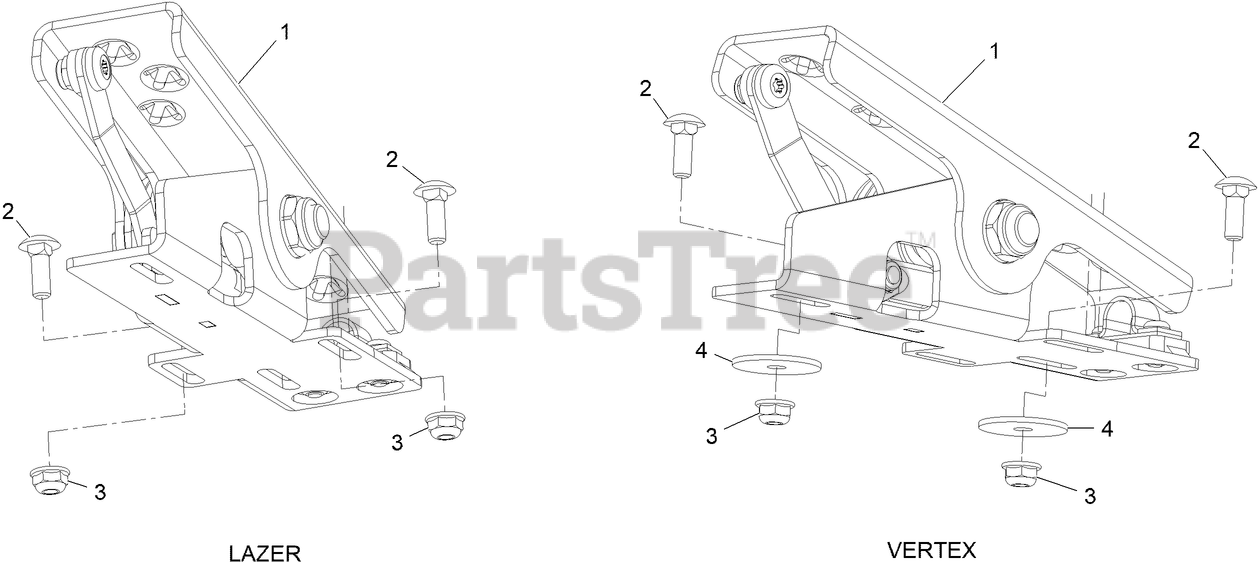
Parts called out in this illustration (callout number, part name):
1	ASM- Pedal
2	BOLT-CARR
4	WASHER-FLAT
